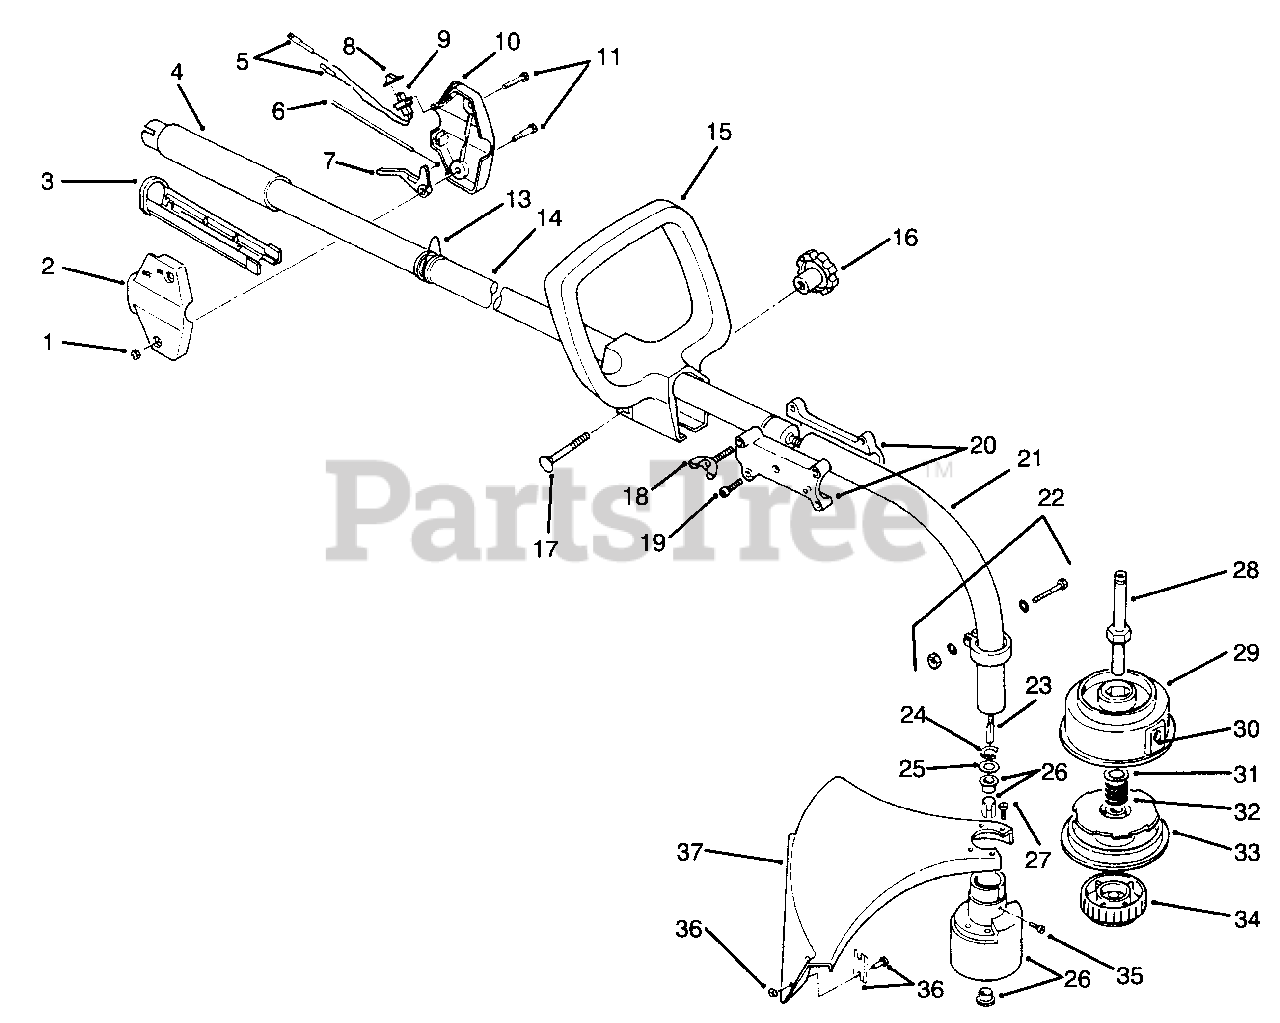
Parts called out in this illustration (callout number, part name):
1	Nut-Lock
2	Housing-R.H.
5	Assembly-Lead Wire
6	Cable-Throttle
7	Lever-Throttle
8	Cap-Switch
10	Housing-L.H.
11	Screw-Hex. Hd.
13	Clamp-Shoulder Strap
14	Assembly-Upper Drive
16	Knob-Loop Handle
17	Bolt-Carriage
18	Knob-Adjustment
19	Bolt Set-Coupling
20	Coupling Set-Split Boom
21	Assembly-Lower Drive
22	Assembly-Lower Clamp
23	Shaft-Flexible Drive
24	Ring-Retaining
26	Assy.-Bushing Housing
27	Assy. Guard Mounting Screw
28	Shaft-Spool
29	Assy.-Outer Spool & Eyelet
31	Retainer
32	Reel-Inner
34	Assy.-Bump Head Knob
35	Screw-Anti-Rotation
36	Assy.-Blade(Incl. 2 Screws & 2 Nuts)
37	Assembly-Guard & Blade(Incl. Ref. No.36)
